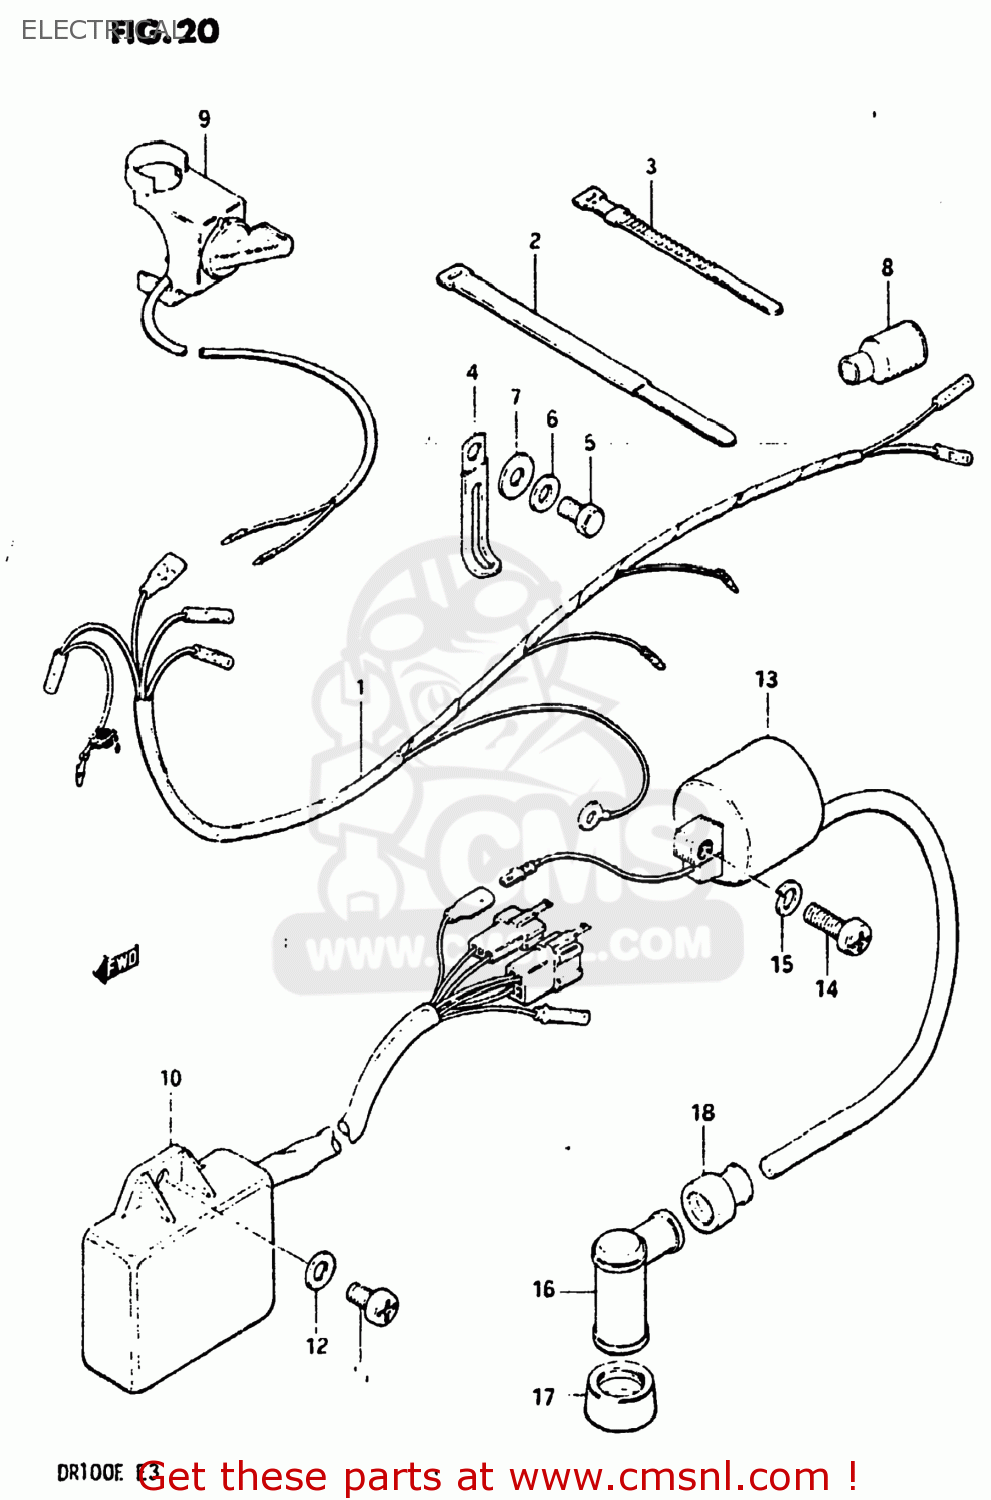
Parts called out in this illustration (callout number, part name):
1	HARNESS,WIRING
2	CLAMP
3	CLAMP(L:120)
4	CLAMP
5	BOLT 6X16
6	WASHER
7	WASHER
8	BOOT,WIRING HARNESS
9	SWITCH ASSY,ENGINE STOP
10	CDI UNIT
11	SCREW
12	WASHER
13	COIL ASSEMBLY,IGNITION
14	SCREW
15	LOCK WASHER
16	CAP ASSY,SPARK PLUG
17	SEAL,SPARK PLUG
18	SEAL,SPARK PLU
